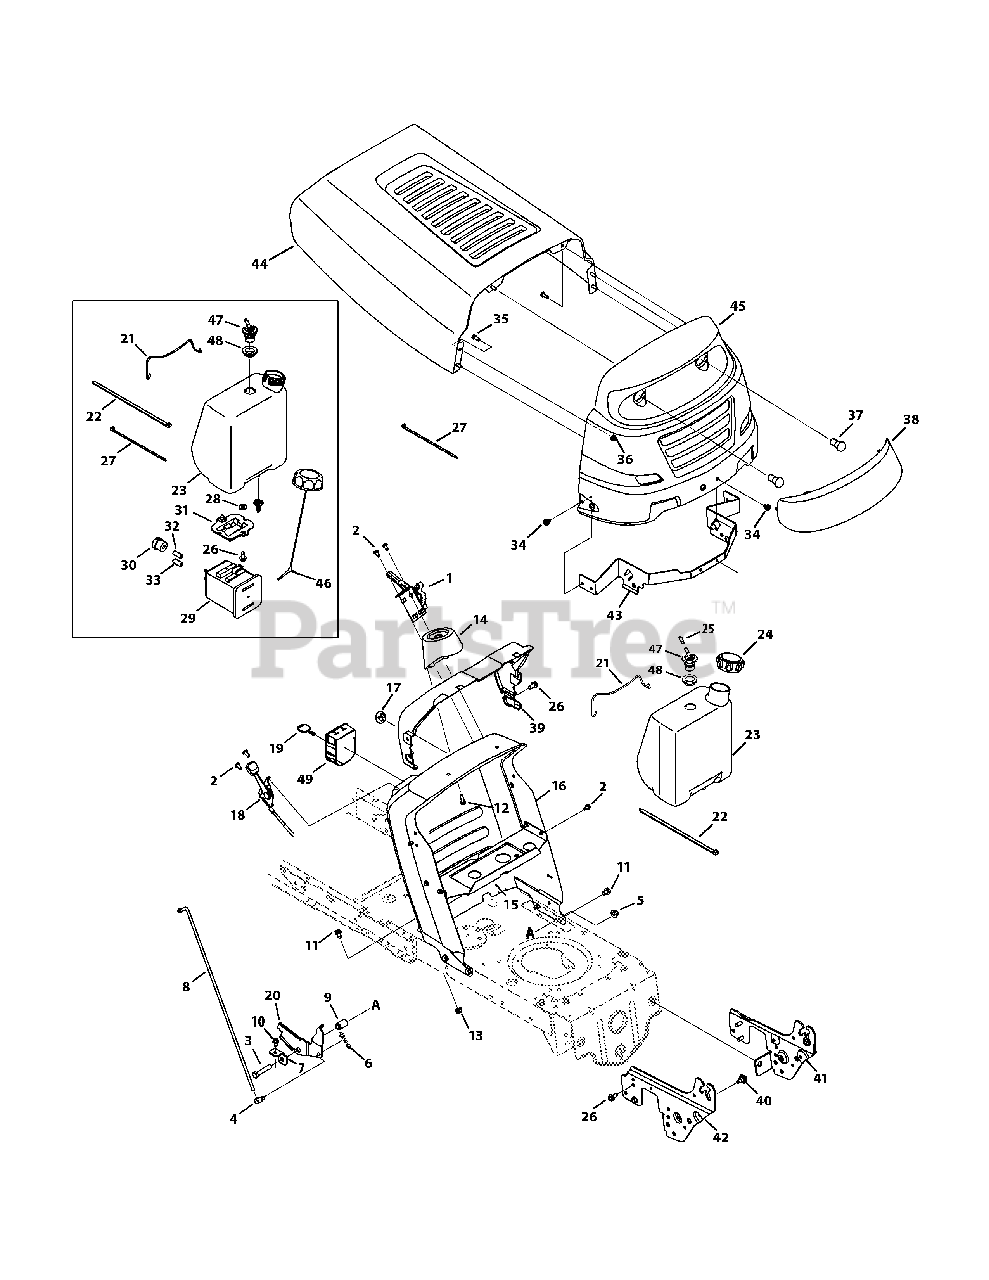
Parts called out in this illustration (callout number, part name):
1	7-Speed Control Assembly
2	Screw, 1/4-20 x .500
3	Hex Screw, 3/8-16 x 2.0
4	Ferrule, 1/4-20 x 1.00
5	Flangelock Nut, 3/8-16
6	Bow-Tie Cotter Pin, 72
7	Speed Latch Tab
8	Speed Selector
9	Flange Spacer, .390 x .671 x 1.095
10	Hex Washer Screw, 1/4-20 x .500
11	Screw, 5/16-18 x .625
12	Screw, 1/4 x .750
13	Flangelock Nut, 5/16-18
14	Steering Support
15	Gas Tank Support Bracket
16	Dash, No RMC - Powder Black
16	Dash, No RMC - Black Jack
17	Choke Plug
18	Throttle/Choke Cable Assembly
20	Speed Latch - No RMC
21	Battery Assembly Rod
22	Cable Tie
23	1.5 Gallon Fuel Tank
23	1.36 Gallon Fuel Tank
24	Fuel Cap
25	Hose Vent, 3/16
26	Screw, 5/16-18 x .750
27	Cable Tie
28	Flat Washer, .344 x .750 x .120
29	5 Gallon Carbon Canister
30	Vent Filter Canister
31	Canister Adapter
32	Fuel Hose, White
33	Fuel Hose, Yellow
34	Screw, 5/16-18 x .375
35	Hex Screw, 1/4-20 x .620
36	Flangelock Nut, 1/4-20
37	Miniature Lamp 12V Socket
38	Lens Grill
39	Dash Collar
40	Shoulder Screw, 5/16-18 x .43 x .29
41	Left Support Pivot Bracket
42	Right Support Pivot Bracket
43	Hood Pivot Bracket
44	Hood - Red
44	Hood - Gray
45	Grille - Red
45	Grille - Gray
46	Fuel Cap, 2.25"
47	Rollover Valve
48	Rubber Grommet, 23 x 3.55
49	Key Switch
